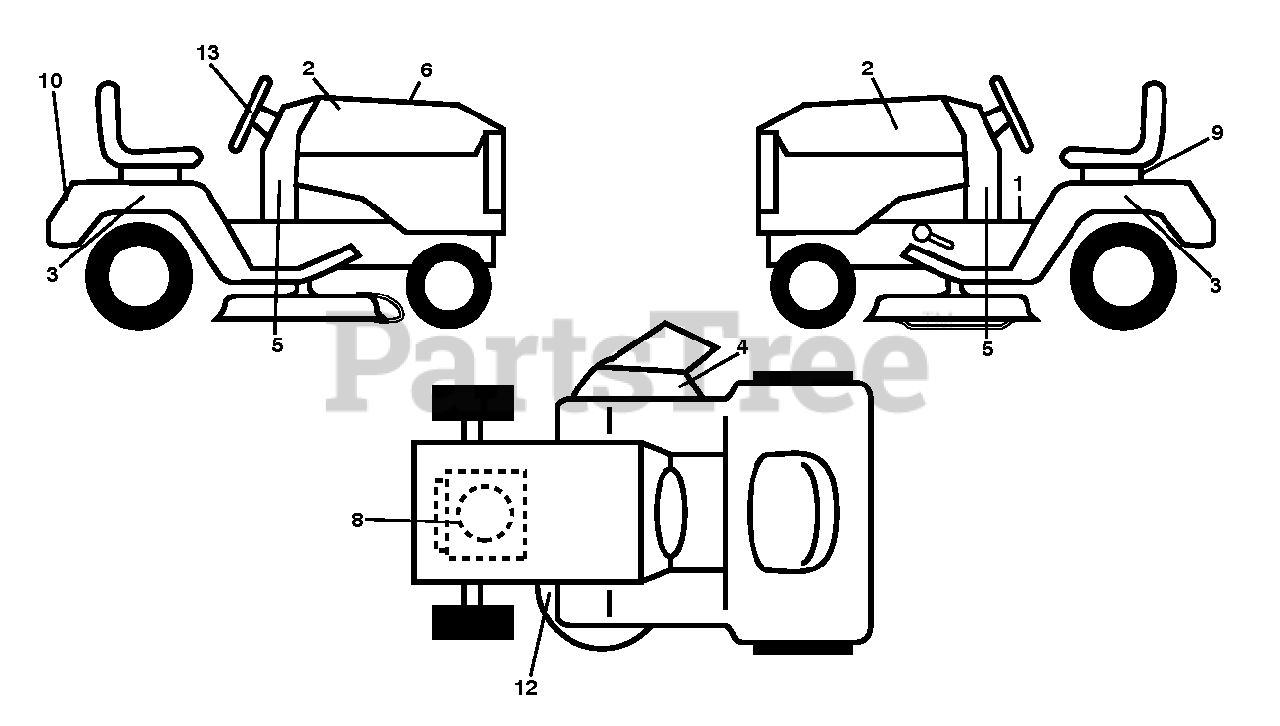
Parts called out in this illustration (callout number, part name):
1	DECAL.WARNING.2007.ENG/FR
2	DECAL.HOOD.ALPHA.RH/LHSET.2014
3	DECAL FENDER
4	DECAL.MOWER.WARN.KEEP.HAND.AWY
5	DECAL.LWRDSH.105HP/38".POULAN
8	DECAL.ENG.BS.10_5PB.DOM.381663
9	DECAL BTRY SYMBOLS
10	DECAL.FNDR.LOGO.2014.POULAN
12	DECAL.DECK.SCH.36,38,94.NONCR
